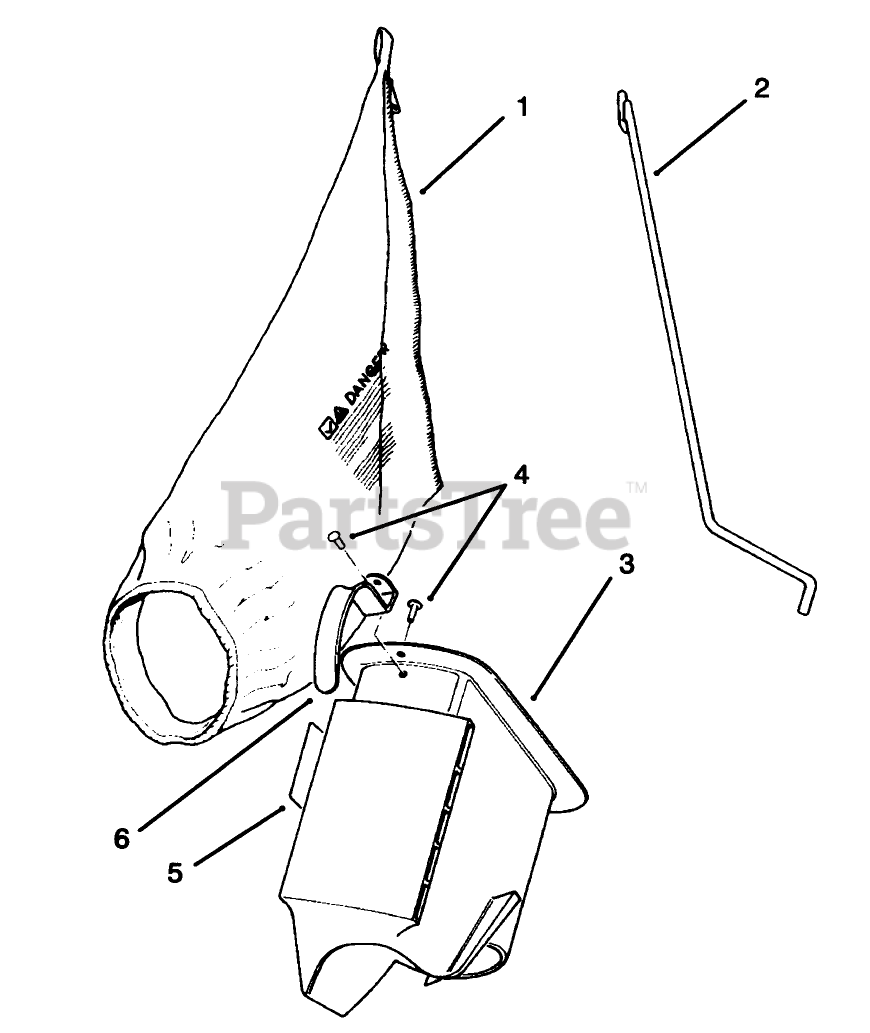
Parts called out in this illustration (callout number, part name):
1	BAG REPLACMNT44-0540
2	BAG ROD
3	Grass Chute Assembly (Incl. Ref. #4 & 6)
4	RIVET 3/16 X 7/16
5	BAG CHUTE DECAL
6	HANDLE-GRASS CHUTE
